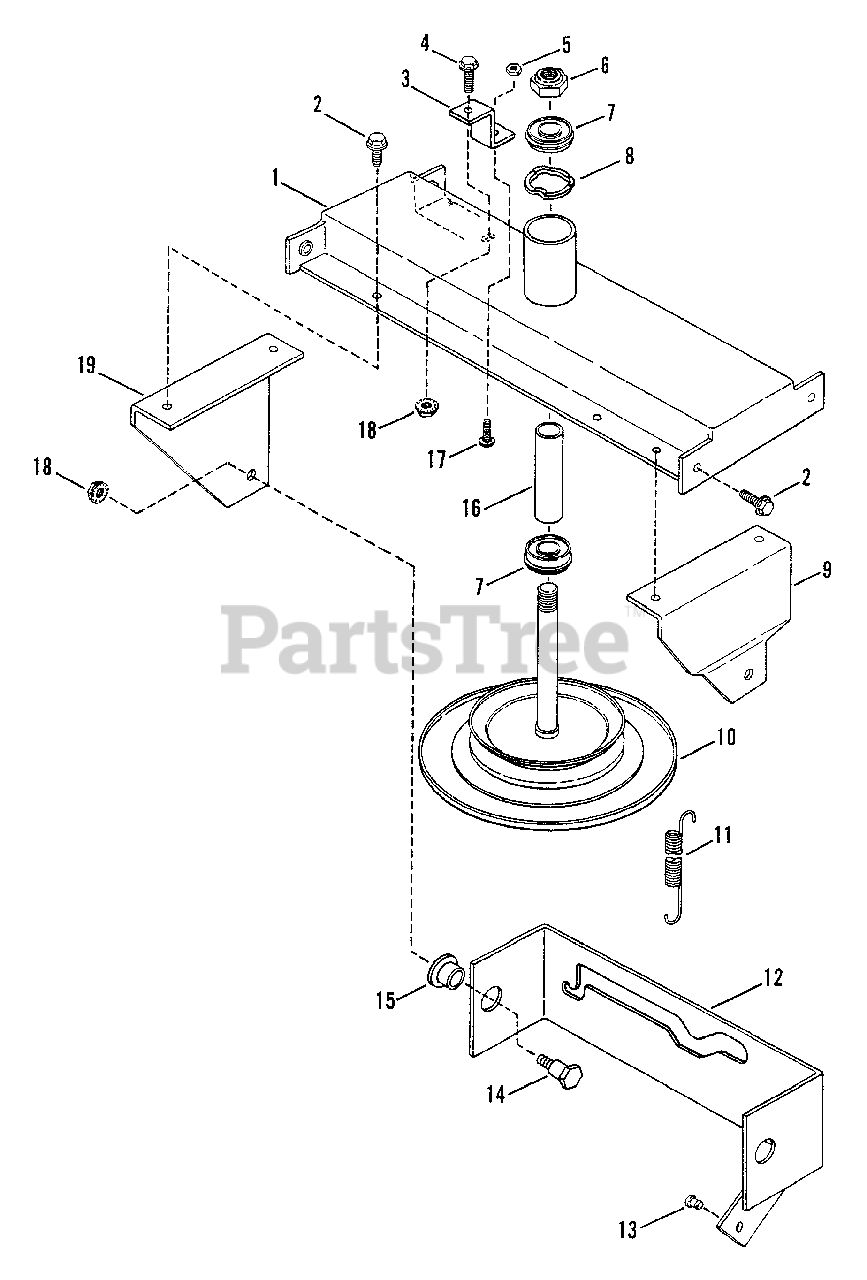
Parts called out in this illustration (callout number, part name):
1	SUPPORT ASSEMBLY, Disc Drive
2	SCREW, 5/16-18 x 1/2" Self-Tapping
3	ASSEMBLY, Yoke Stop
4	BOLT, 5/16-18 x 3/4" Hex Flange Lock
5	NUT, 5/16-18 Hex Jam
6	NUT, 5/8-18 Hex Lock
7	BEARING
8	WASHER, Wave
9	BRACKET, Yoke Pivot (Left Hand)
10	ASSEMBLY, Disc Drive
11	SPRING
12	YOKE, Clutch
13	BEARING, Nyliner
14	BOLT, 5/16-18 x 1-5/16" Shoulder
15	BEARING, Yoke
17	BOLT, 5/16-18 x 1-1/2" Carriage
18	NUT, 5/16-18 Hex Flange Lock
19	BRACKET, Yoke Pivot, R.H.
